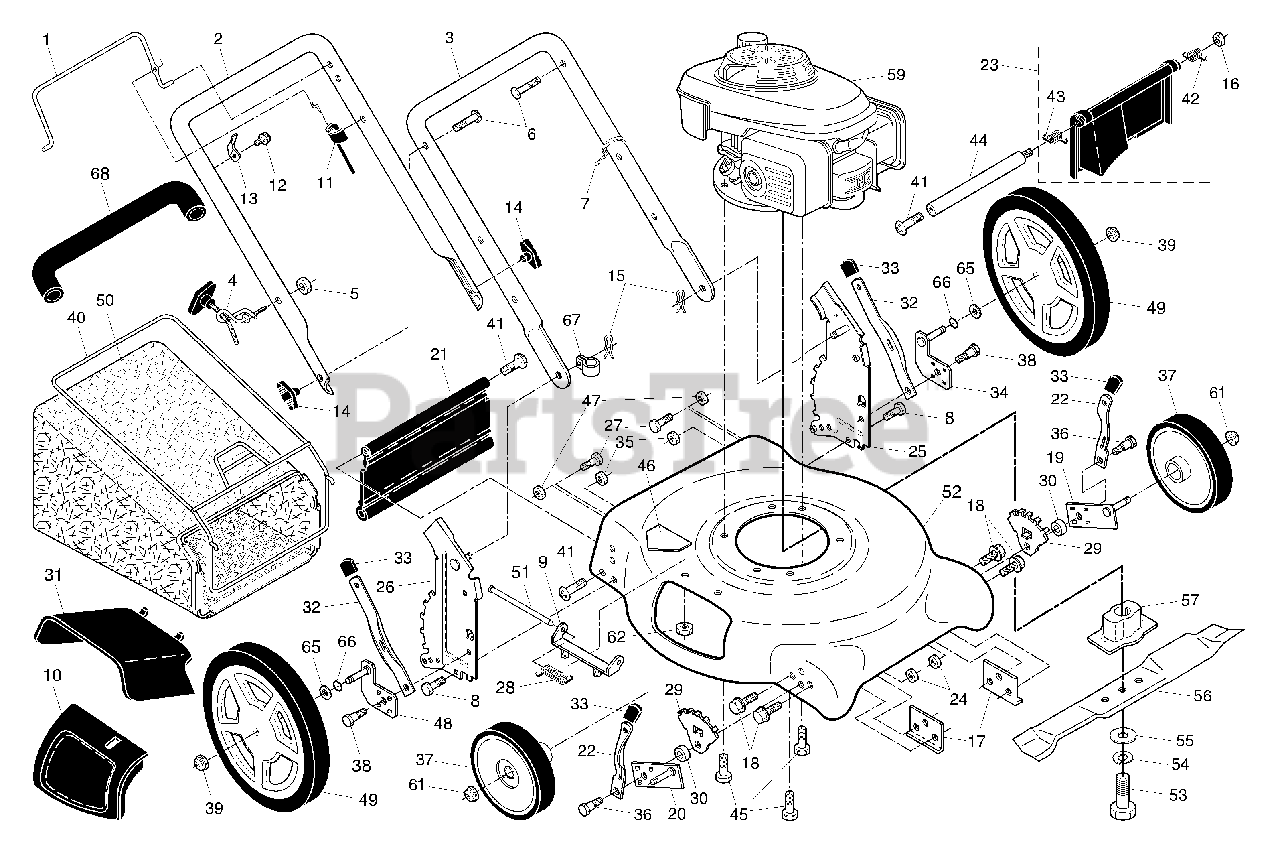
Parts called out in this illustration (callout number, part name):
1	Control Bar
2	Upper Handle
3	Lower Handle
4	Rope Guide
5	Locknut, Hex 1/4-20
6	Handle Bolt
7	Wire Tie
8	Hex Bolt 5/16-18 x 3/4
9	Hinge Bracket Assembly
10	Mulcher Door
11	Engine Zone Control Cable
12	Hex Washer Head Screw #10-24 x 1/2
13	Up-Stop Bracket
14	Handle Knob
15	Hairpin Cotter
16	Nut, Hex, Flangelock 1/4-20
17	Support Bracket
19	Axle Arm Assembly, Front, LH
20	Axle Arm Assembly, Front, RH
21	Rear Skirt
22	Selector Spring, Front
23	Kit, Rear Door
24	Locknut, Hex 5/16-18
25	Handle Bracket Assembly, LH
26	Handle Bracket Assembly, RH
27	Screw 1/4-20 x 3/8
28	Spring, Torsion
29	Wheel Adjusting Bracket, Front
31	Discharge Deflector
32	Selector Spring, Rear
33	Selector Knob
34	Axle Arm Assembly, Rear, LH
35	Locknut, Hex 5/16-18
36	Shoulder Bolt 5/16-18
37	Wheel & Tire Assembly, Front 8 x 1-3/4
38	Shoulder Bolt
39	Nut, Hex, Flangelock
40	Frame, Grassbag
41	Hinge Screw
42	Spring, Rear Door, LH
43	Spring, Rear Door, RH
44	Rod, Rear Door
45	Hex Head Thread Rolling Screw 3/8-16 x 1
46	Danger Decal
48	Axle Arm Assembly, Rear, RH
49	Wheel & Tire Assembly, Rear 12 x 1-3/4
50	Grassbag
52	Kit, Lawn Mower Housing Assembly
53	Hex Head Screw 3/8-24 x 1-3/8 Grade 8
54	Helical Lockwasher
55	Hardened Washer
57	Blade Adapter
61	Nut, Hex, Flangelock
62	Nut, Hex, Nylock 1/4-20
65	Washer, Flat
67	Clip, Cable
68	Grip, Foam
